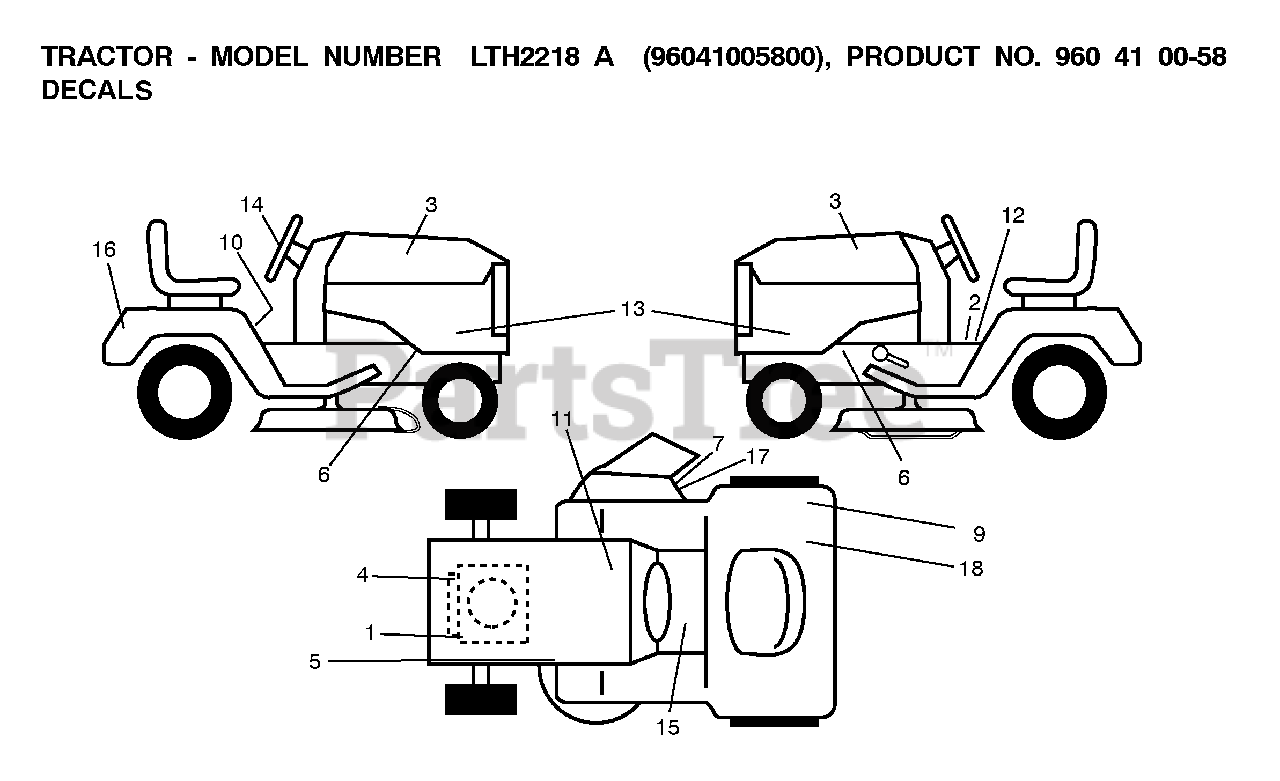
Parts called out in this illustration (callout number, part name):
2	DECAL PARK BRAKE
5	DECAL V BELT SCHEMATIC
7	DECAL.INTERNATIONL.CUTFINGER
11	DECAL BTRY SYMBOLS
17	DECAL, DEFLECT WARNING
18	DECAL.80 DBA.AUSTRALIA
